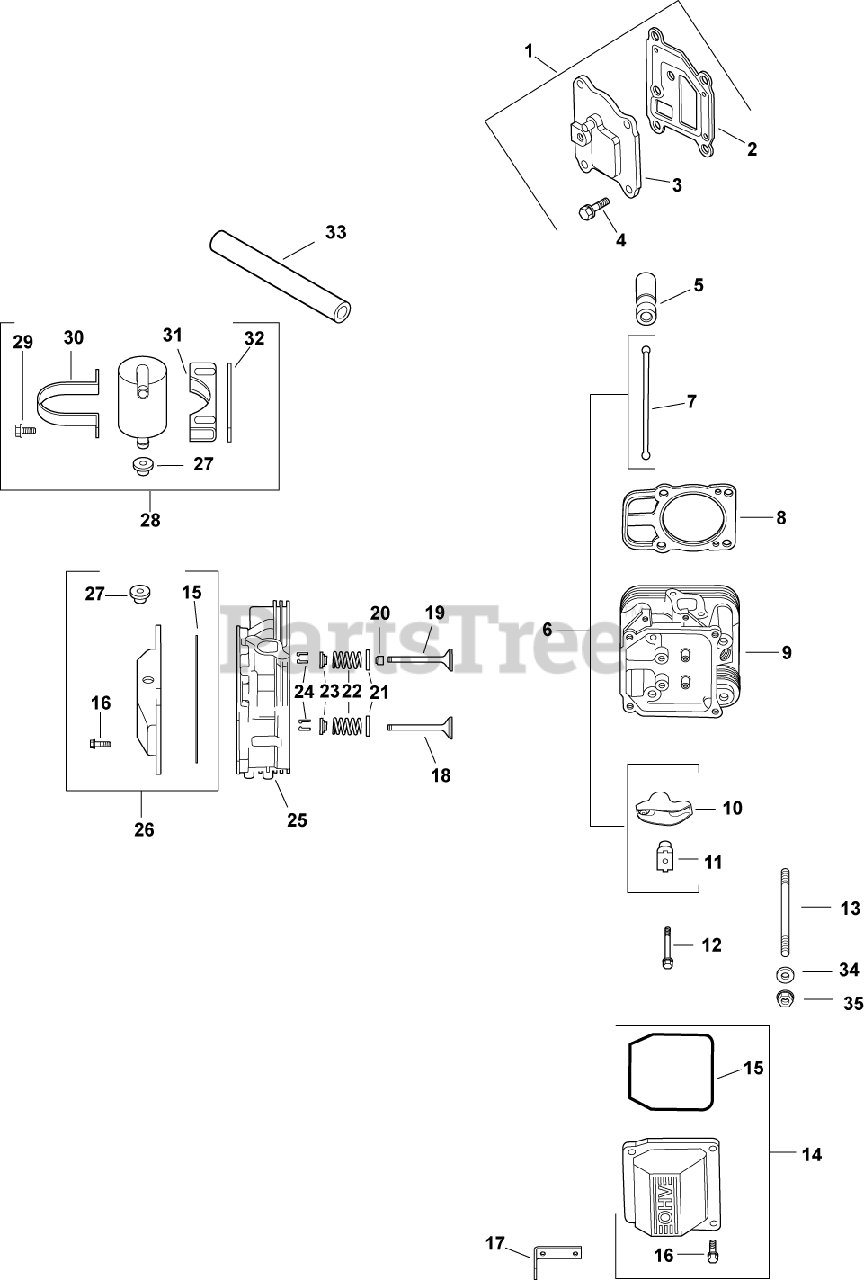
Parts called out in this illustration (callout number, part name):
1	KIT, BREATHER COVER W/GASKET
2	GASKET, BREATHER
3	COVER, BREATHER -USE 24 096 125-S
4	SCREW,FLG THD FRM M6X1.0X20-(#25086396S)
5	LIFTER, VALVE HYDRAULIC-USE 25 351 10-S
6	KIT, VALVE TRAIN
7	ROD, PUSH
8	CYL HEAD GASKET KIT-USE 24 841 04-S
9	KIT, CYLINDER HEAD #2
10	ARM, ROCKER
11	PIVOT, ROCKER ARM
12	SCREW, FLG M6X1.0X34
13	STUD, M8X1.25
14	KIT, VALVE COVER-PLAIN
15	O-RING (YELLOW), VALVE COVER
16	SCREW, FLG M6X1.0X30
17	STRAP, LIFTING-USE 25 445 03-S
18	VALVE, EXHAUST (STD) - USE 32 016 01-S
19	VALVE, INTAKE (STD)
20	SEAL, VALVE STEM - (#2503214S)
21	RETAINER, SPRING
22	SPRING, VALVE
23	CAP, VALVE SPRING
24	KIT, RETAINER
25	KIT, CYLINDER HEAD #1
26	KIT, VALVE COVER
27	GROMMET, RUBBER
28	KIT, BREATHR SEPARATR-(#24755241S)
29	SCREW,FLG THD FRM M5X0.8X16-(#25086398S)
30	STRAP, BREATHER - USE 24 755 241-S
31	BRACKET, BREATHER SEPARATOR
32	SPACER
33	HOSE, BREATHER-USE 24 326 63-S
34	WASHER, FLAT 8.6 MM
35	NUT, FLG M8X1.25
2401602-S	VALVE, EXHAUST (.25)
2401702-S	VALVE, INTAKE (.25)
